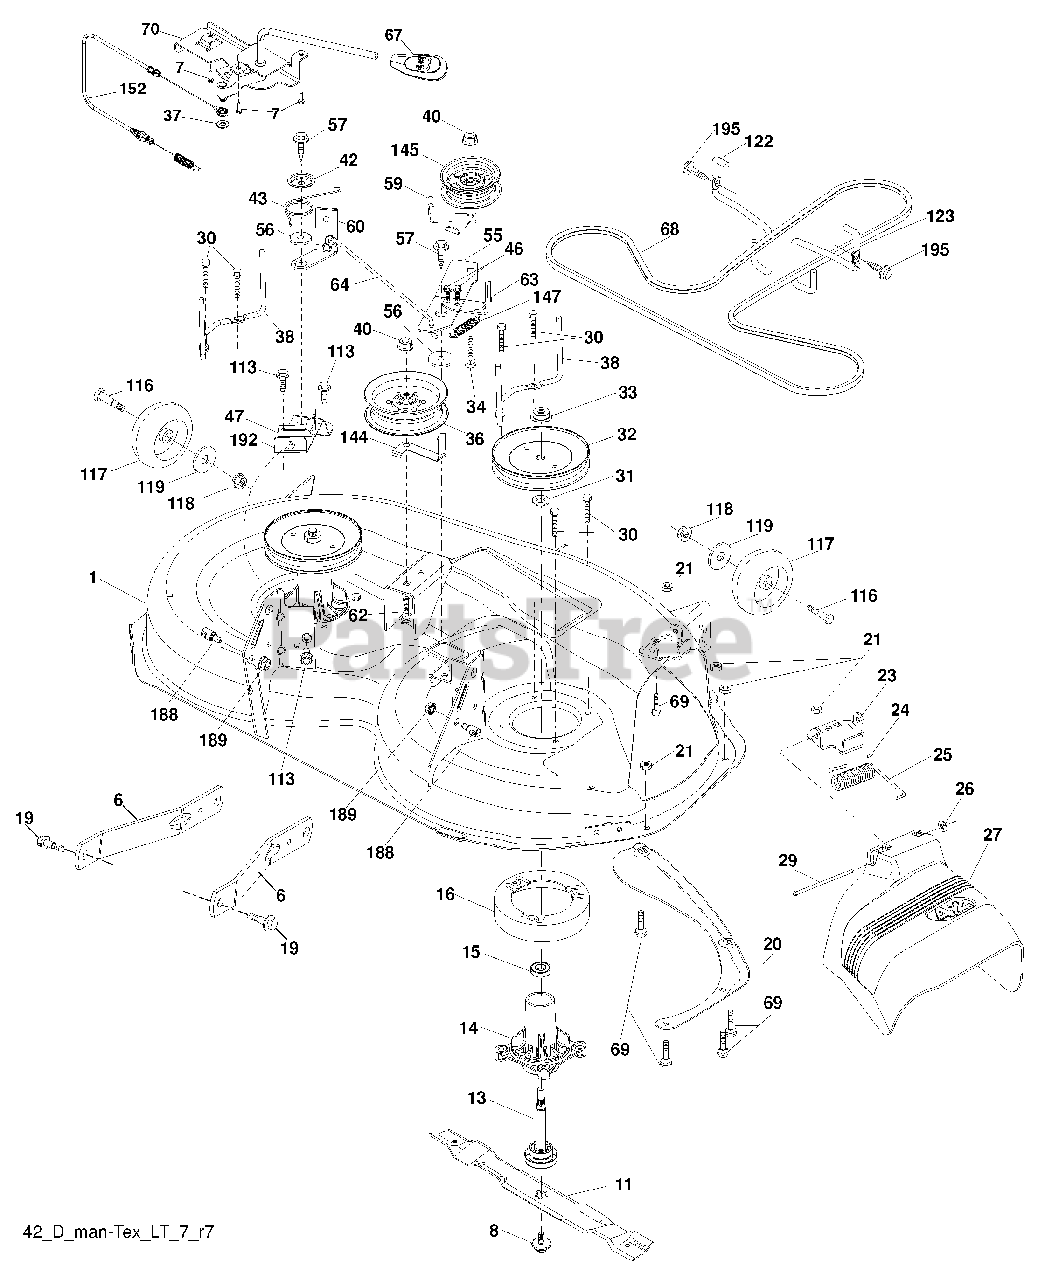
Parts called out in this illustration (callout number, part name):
6	Arm Suspension
7	Screw 10 x 3/4 Single Hex
8	Bolt/Washer Asm 7/16-20 unf
8	Blade, 42" Mulching Premium (For better wear when mulching)
11	Blade, 42" Hi-Lift (For bagging or discharge)
11	Blade, 42" Mulching Std (For mulching mowers only)
13	Shaft Assembly, Mandrel
14	Housing, Mandrel
15	Bearing, Ball, Mandrel
16	Stripper, Mower Deck
19	Bolt, Shoulder
20	Baffle, Vortex
21	Nut, Crownlock 5/16-18 unc
23	Bracket, Deflector
24	Cap, Sleeve
25	Spring, Torsion, Deflector
26	Nut, Push
27	Shield, Deflector
29	Rod, Hinge
30	Screw Thdrol Rolling Wsh Hd
31	Washer, Spacer
32	Pulley, Mandrel
33	Nut, Toplock, Flanged
34	Bolt Carr Sh. 3/8-16 x 1-1/2 Gr.
36	Pulley, Idler, Flat
37	Washer 13/32 x 13/16 x 16 Ga.
38	Keeper Belt LH Mandrel
40	Nut, Lock Flg. 3/8-16 unc
42	Spring Torsion Brake
43	Spring Torsion Retainer
46	Screw Thd Roll 1/4-20 x 5/8
47	Bracket Clutch Cable
55	Arm, Idler
56	Spacer, Retainer
57	Screw Hexwsh Thd 3/8-16 x 1
59	Guard, Tuv Idler (94)
60	Arm Brake Mower
62	Bolt Rdhd Sqnk 3/8-16 unc x 2
63	Arm Brake Mower
64	Linkage Brake
67	Handle, Clutch Cable
68	V-Belt
69	Bolt Rdhd Sqnk 5/16-18 x 5/8
70	Clutch Asm. Manual
113	Screw 5/16-18
116	Bolt
117	Wheel Gauge
118	Nut Lock 3/8-16 unc
119	Washer 3/8-7/8 x 14 Ga.
122	Keeper Belt Eng. LH
123	Keeper Belt Eng. RH
144	Keeper Belt
145	Pulley Idler
147	Spring Return
152	Cable Clutch Manual w/Spr.
188	Stud Fastener
189	Nut Lock Hex Flange
192	Bracket Brake Stand LH
195	Screw Hexwsh Thdr 3/8-16 x 3/4
195	Mandrel Assembly
195	Replacement Mower, Complete
